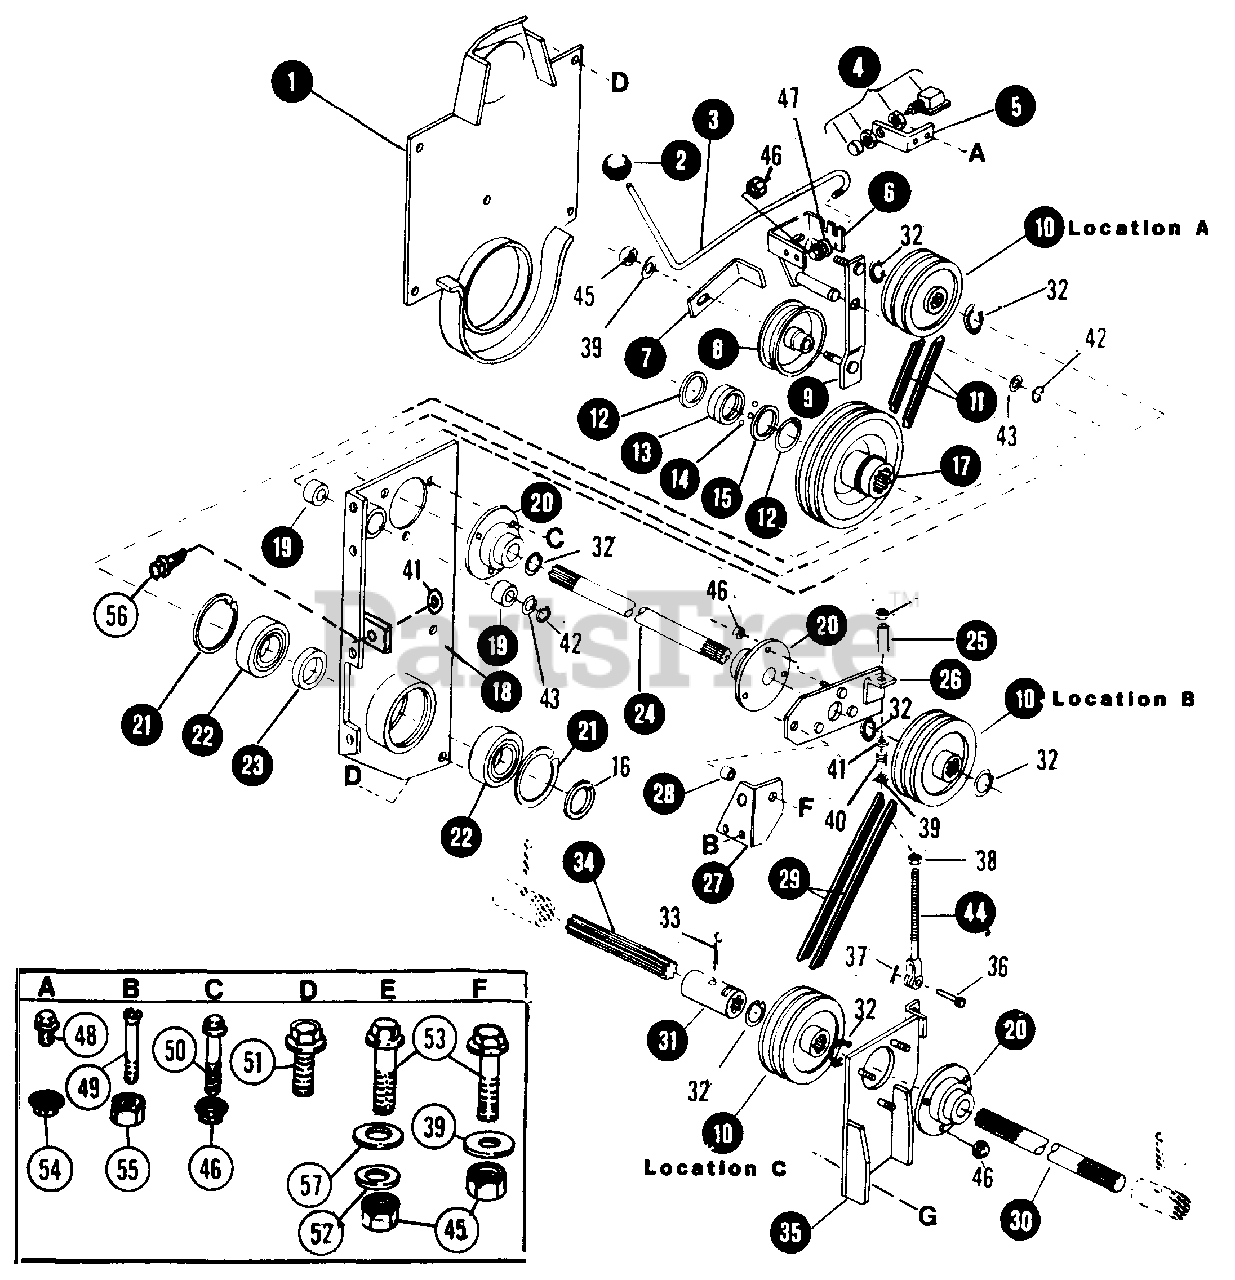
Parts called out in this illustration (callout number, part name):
1	COVER, REAR
2	KNOB, P.T.O. CONTROL LEVER
3	LEVER, REAR P.T.O. CONTROL
4	SWITCH, P.T.O. INTERLOCK
5	BRACKET, SWITCH MOUNTING
6	BRACKET, IDLER ASSEMBLY
7	GUIDE, V-BELT
8	PULLEY IDLER, 3/8" ID, 4.0" OD, 1.25" Wide
9	ARM, IDLER - ASSEMBLY
10	PULLEY DRIVE
11	V-BELTS (SET) REAR P.T.O. DRIVE
12	RING, RETAINING
13	COLLAR, SHAFT LOCK
14	BALL, STEEL 3/8" DIAMETER
15	SPRING, SLIDING RETAINING
16	RING, RETAINING
17	PULLEY, DRIVE
18	PLATE, MOUNTING - ASSEMBLY
19	BUSHING, MOUNTING PLATE
20	BEARING, 3 Hole Flanged Lock Collar Assy., 3/4" ID
21	RING, RETAINING
22	BEARING, P.T.O. PULLEY, 1.37" ID, 2.83" OD, .66" Wide
23	SPACER, STEEL
24	SHAFT, REAR DRIVE
25	SLEEVE, ROD GUIDE
26	BRACKET, P.T O. SHAFT
27	BRACKET, PIVOT
28	SPACER, PIVOT
29	V-BELTS (SET) P.T.O. DRIVE
30	SHAFT, FRONT DRIVE
31	COUPLING, SHAFT
32	RING, RETAINING
33	COTTER-PIN, 3/32 x 3/4
34	SHAFT, REAR P.T.O. DRIVE
35	BRACKET, DRIVE SHAFT
36	PIN, CLEVIS
37	COTTER-PIN, 3/32 x 3/4
38	NUT, 3/8C - SPECIAL
39	WASHER, 3/8" Flat
40	SPRING, ROD GUIDE
41	WASHER, 1/2" FLAT
42	RING, RETAINING
43	WASHER, 5/8 x 1 x .020
44	ROD GUIDE ASSEMBLY
45	NUT, 3/8C HEX FLANGE LOCK
46	NUT, 5/16C HEX FLANGE LOCK
47	SPACER, LEVER TO BRACKET
48	BOLT, 1/4C x 1/2 HEX FLANGE LOCK
49	SCREW, 1/4C x 7/8 FLAT HEAD
50	BOLT, 5/16C x 7/8 HEX FLANGE LOCK
51	BOLT, 3/8C x 3/4 HEX FLANGE LOCK
52	WASHER, 5/8 x 1-1/4 x .010
53	BOLT, 3/8C x 1-1/4 HEX FLANGE LOCK
54	NUT, 1/4C HEX FLANGE LOCK
55	NUT, 1/4C HEX
56	BOLT, 1/2-13 x 3/4 HEX FLANGE LOCK
57	WASHER, 3/8 x 1-1/4 x 1/8
